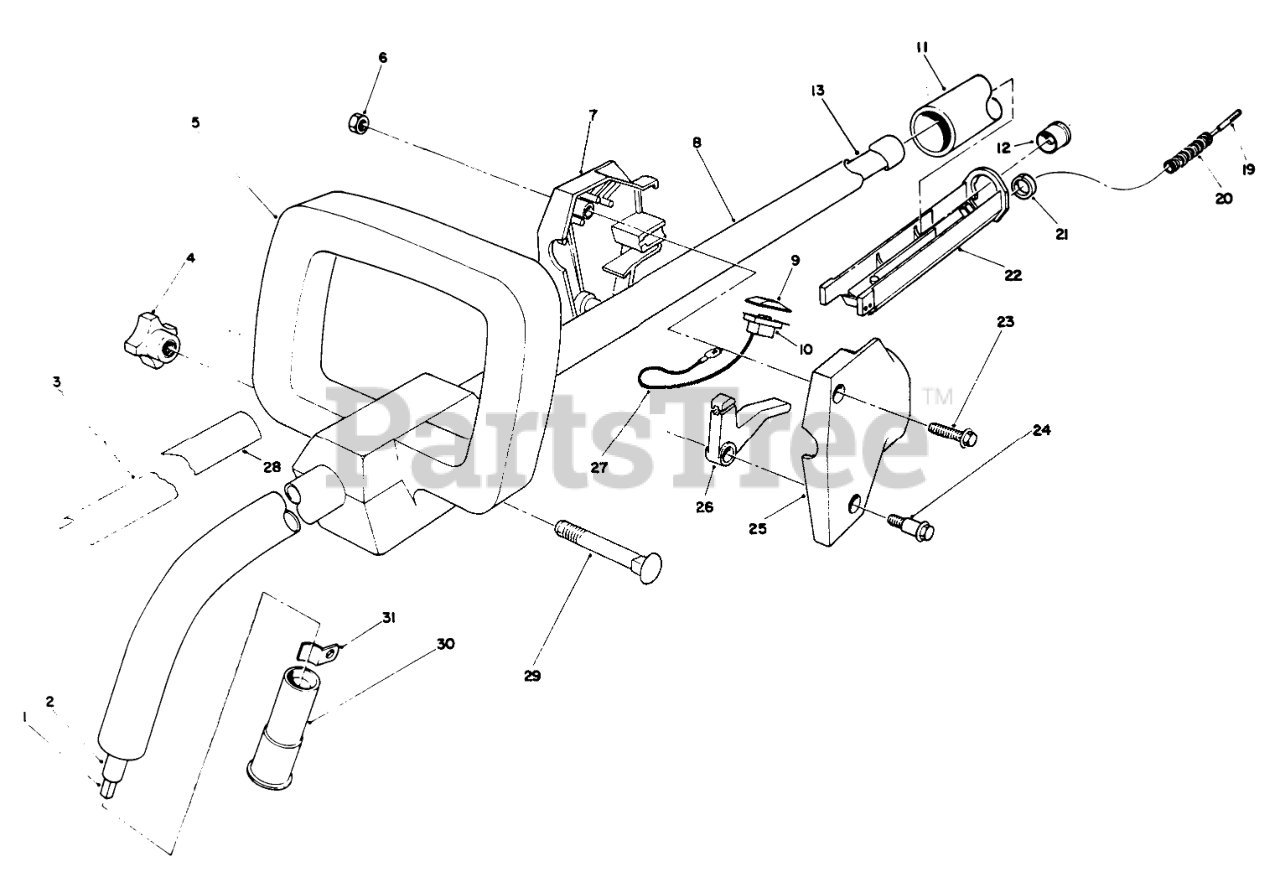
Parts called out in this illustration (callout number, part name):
1	FLEX SHAFT
2	FLEX SHAFT CASING
3	DECAL - TC 2010
4	Knob
5	SECONDARY HANDLE
6	NUT-LOCK, NI
7	RH HOUSING
8	Tube-Curved
9	SWITCH COVER
10	SWITCH
11	GRIP-RUBBER
12	BUSHING
13	Spacer
19	THROTTLE CABLE
20	CABLE COVER
21	RING FITTING
22	TROUGH
24	SCREW-SHOULDER
25	LH HOUSING
26	THROTTLE LEVER
27	WIRE ASM
28	Decal
29	BOLT-CARRIAGE
30	INSERT-POLE END
31	LOWER TUBE RETAINER
